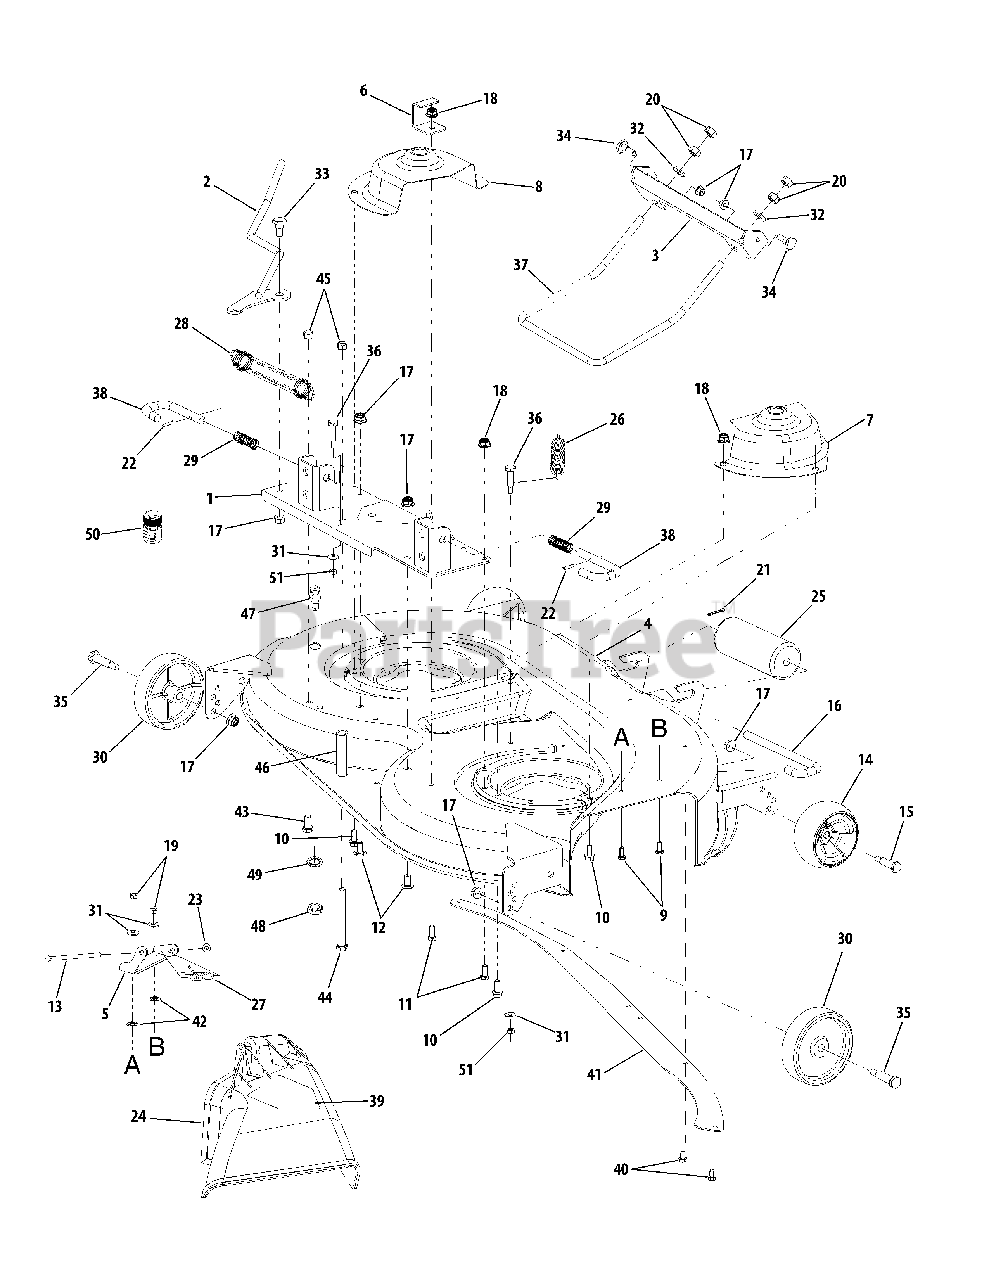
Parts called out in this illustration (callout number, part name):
1	Plate Assembly, Mounting
2	Handle, Tension
3	Bracket, Front Lift
4	Deck Assembly, 42"
5	Bracket, Hinge Mounting
6	Bracket, Handle Stop
7	Shield, RH Pulley
8	Shield, LH Pulley
9	Screw, Hex Cap, 1/4-20 x .62 GR5
10	Screw, Hx Wsh Hd Tapp, 5/16-18 x .75
11	Screw, Hex Cap, 5/16-18 x .75 GR5
12	Bolt, Carriage, 3/8-16 x .75
13	Pin, Hinge, .25 Dia x 6.75 Lg
14	Wheel, Deck
15	Bolt, Shoulder, 1/2 x 2.5 : 3/8-16
16	Pin, Roller, 1/2 Dia x 7.31 Lg
17	Nut, Hex Flange Lock, 3/8-16
18	Nut, Hex Flange Lock, 5/16-18 GR5
19	Nut, Hex, 1/4-20
20	Nut, Hex, 1/2-13
21	Pin, Cotter, 3/32 x 1.25
22	Pin, Spirol Spring, 3/16 x .75
23	Cap, Speed Nut
24	Deflector Assy, Includes 5, 13, 27, and 42
25	Roller
26	Spring, Extension, .88 OD x 6.12
27	Spring, Torsion
28	Spring, Extension, 1.25 OD x 8.15
29	Spring, Compression
30	Wheel, Deck, 5 in. Dia
31	Washer, Bell, .265 x .75 x .062
32	Washer, Flat, .531 x 1.062 x .134 HT
33	Bolt, Shoulder, .498 Dia x .340 Lg
34	Bolt, Shoulder, .50 Dia x .434 Lg
35	Bolt, Shoulder, 1/2 x 1.5 : 3/8-16
36	Bolt, Shoulder, .375 Dia x 1.16 Lg
37	Rod, Front Lift
38	Pin, Mower Support
39	Graphic, Danger
40	Screw, Self Tapping, 1/4-20 x .5
41	Skirt, Deck
42	Nut, Push, 1/4
43	Screw, Hx Cap Lock, 3/8-24 x .75 GR5
44	Screw, Hex Cap, 3.8-24 x 3.75 GR5
45	Nut, Hex Insert Lock, 3/8-24
47	Nozzle, Deck Wash
48	Nut, Hex, M16-1.5
49	Washer, Internal Tooth Lock
50	Adapter, Water Nozzle
51	Nut, Hex Flange Lock, 1/4-20 GrF
